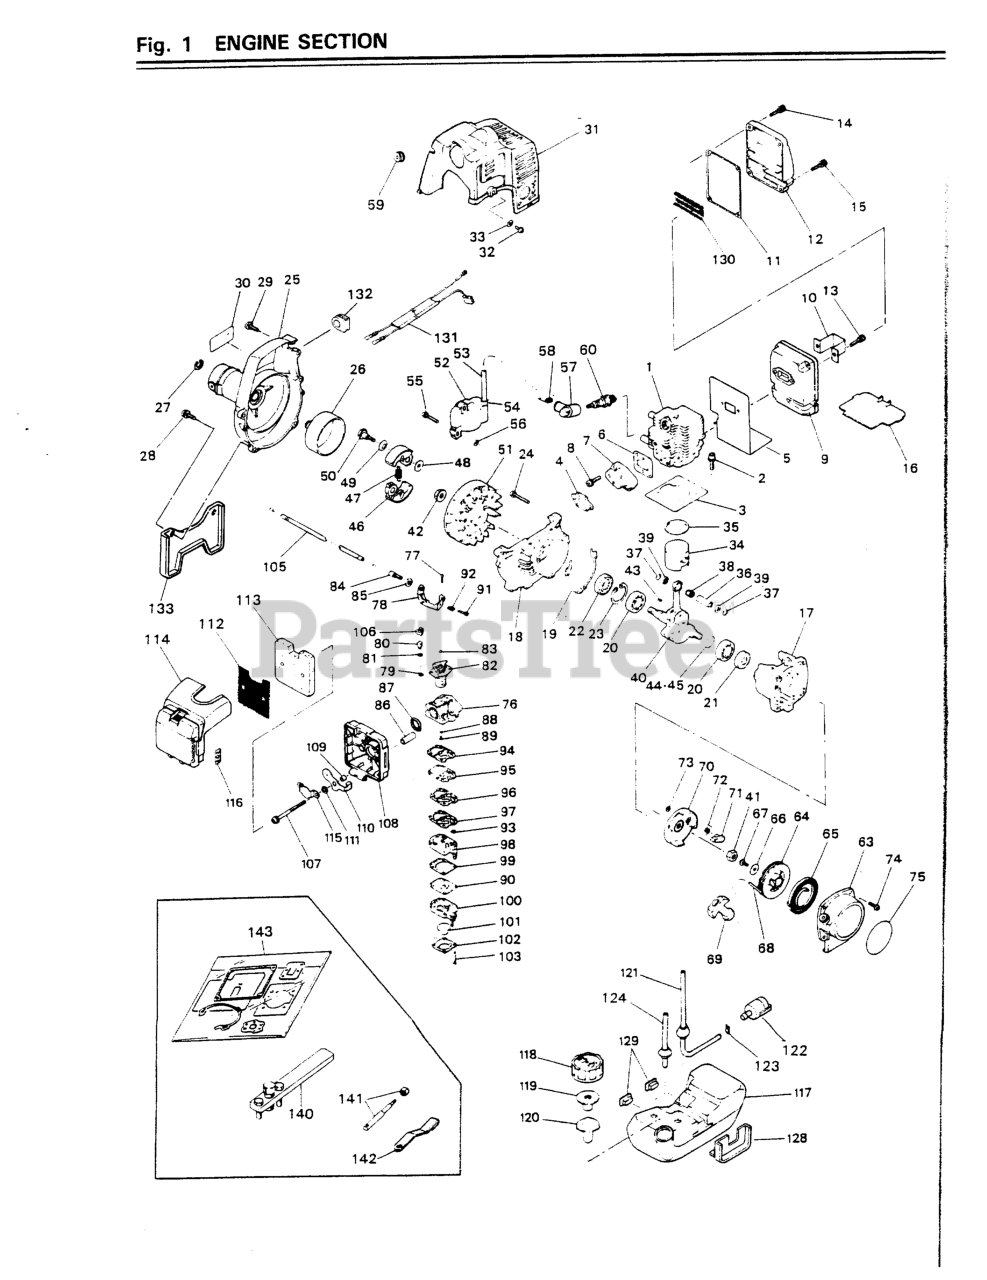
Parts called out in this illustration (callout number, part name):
2	BOLT, M5 X 22
8	SCREW, M5 X 20
13	BOLT, M6 X 18
14	BOLT, M5 X 22
15	BOLT (USE 3310-31720)
17	CRANKCASE (RPLS -21100)
18	CRANKCASE (RPLS -21100)
20	BEARING
22	SEAL, OIL (RPLS 1140-21220)
23	RING, SNAP, M28 x 1.2
24	SCREW, M5 x 30(RPLS 0263-00530
27	RING, SNAP
28	SCREW, M5X20 (RPLS.1400-75510)
29	SCREW, HOUSING
32	SCREW, M4 x 12
33	WASHER
34	PISTON
35	RING, PISTON (RPLS 1850-41210)
36	PIN, PISTON 5x8x26
37	RING, SNAP (RPLS 1101-41320)
39	WASHER
43	KEY
45	SHIM (NO LONGER AVAILABLE)
48	WASHER, FLAT (USE 182303)
50	BOLT
52	COIL
53	CORD
54	CAP
55	SCREW, M4 X 22
58	SPRING
59	GROMMET
63	RECOIL
64	REEL
65	SPRING, SPIRAL
66	WASHER (NO LONGER AVAIL)
72	SPRING, RETURN
73	E-RING
74	SCREW, M4 X 16
75	LABEL
77	SCREW
79	RING
80	SWIVEL (USE -06040)
81	WASHER
82	VALVE ASSY (NO L0NGER AVAIL)
83	PLUG NEEDLE
85	NUT, CABLE ADJUSTER
86	SLEEVE, MOUNT
87	RING, PACKING (NLA)
88	RING, O
90	DIAPHRAGM (USE 4810-81260)
91	SCREW, IDLE AD
92	SPRING, IDLE A
94	GASKET, PUMP
95	DIAPHRAGM
96	PLATE, PUMP (NLA)
97	GASKET, PLATE
98	BODY, PUMP
99	KIT ONLY
101	PUMP, PRIMING
102	COVER
103	SCREW
105	CABLE COMP (RPLS 1633-83100)
106	CAP, CABLE END
108	BODY (RPLS -82110)
109	SLEEVE
112	SCREEN
113	ELEMENT
114	COVER
115	PLATE
116	LABEL
118	CAP (USE 5601-85201)
119	VALVE (NO LONGER AVAILABLE)
121	PIPE COMP (NO LONGER AVAIL)
122	5500-85400 (RRLS. 1750-85300)
123	CLIP (REPLACES 2841-31280)
128	CUSHION (S)
129	CUSHION (F)
130	ARRESTER
141	(H) ROD ASSY
142	STOPPER (TOOL) (RPLS -96410)
NI	CLEANER ASSEMBLY (NLA)
NI	DIA/GASK KIT, 220,260,230
NI	KIT, REBUILD, BT/BC220
